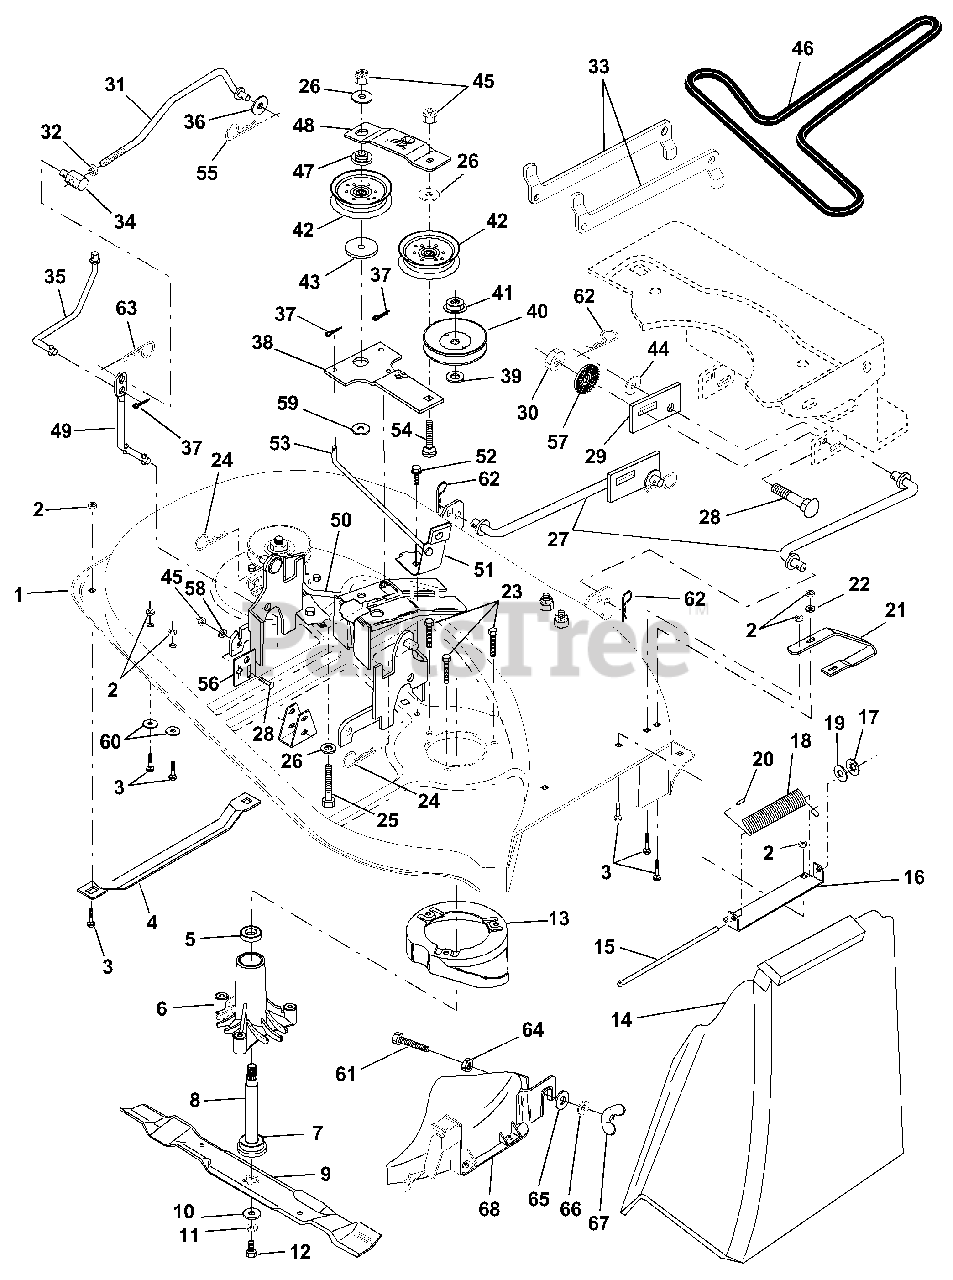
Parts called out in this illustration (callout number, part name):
1	Mower Deck Assembly
2	Nut, Crownlock 5/16-18
3	Bolt, Carriage 5/16-18 x 3/4
4	Runner, L.H.
6	Housing, Mandrel
8	Shaft and Bearing Assembly, Mandrel
10	Washer, Hardened
11	Washer, Lock 3/8
12	Bolt, Hex 3/8-24 x 1-1/4 Grade 8
13	Stripper, Mower, Vented
14	Shield, Deflector
15	Rod, Hinge
16	Bracket Assembly, Deflector
18	Spring, Deflector
19	Washer 11/32 x 5/8 x 16 Gauge
20	Cap, Sleeve
21	Runner, R.H.
22	Washer 11/32 x 3/4 x 16 Gauge
23	Screw Thdrol Hex Head Zinc MWR
24	Retainer, Spring
25	Bolt Hex 3/8-16 x 2-1/4
26	Washer 13/32 x 1 x 12 Gauge
27	Link Assembly, Front
28	Bolt RDHD SQNK 3/8 - 16 x 1
29	Plate Slide Link
30	Nut, Lock Hex w/washer 3/8 - 16
31	Clutch Rod, Primary
32	Nut, Hex, Jam 3/8-16
33	Arm, Suspension, Rear
34	Trunnion 3/8-16
35	Clutch Rod, Secondary
36	Washer 13/32 x 13/16 x 16 Gauge
37	Pin, Cotter 3/32 x 3/4
39	Washer .150 Thick
40	Pulley, Mandrel
41	Nut, Flangelock 9/16
42	Pulley, Flat Idler
43	Spacer, Retainer
44	Washer 13/32 x 1 x 12 Gauge
45	Nut, Crownlock 3/8-16
46	Belt
47	Spacer, Idler Arm
48	Stiffener, Idler Arm
49	Rod, Pivot
50	Rod, Brake, L.H.
51	Brake Assembly
52	Screw, Hex Washer Head, Thd., Roll. 5/16-18 x 3/4
53	Rod, Brake, R.H.
54	Bolt, Carriage 3/8-16 x 1-3/4 Grade 5
55	Spring, Retainer
56	Adjustment Plate, Rear Link, L.H.
57	Rondelle 13/32 x 1
58	Washer 13/32 x 3/4 x 12 Gauge
59	Washer Hardened
60	Washer 11/32 x 11/16 x 12 Gauge
61	Bolt 3/8-16 X 1-1/4
62	Retainer Spring
63	Retainer Spring
64	Nut Centerlock 3/8-16
65	Washer 13/32 X 1-1/4 X 16
66	Washer, Lock, Hvy
68	Cover Asm. Mulching 38
